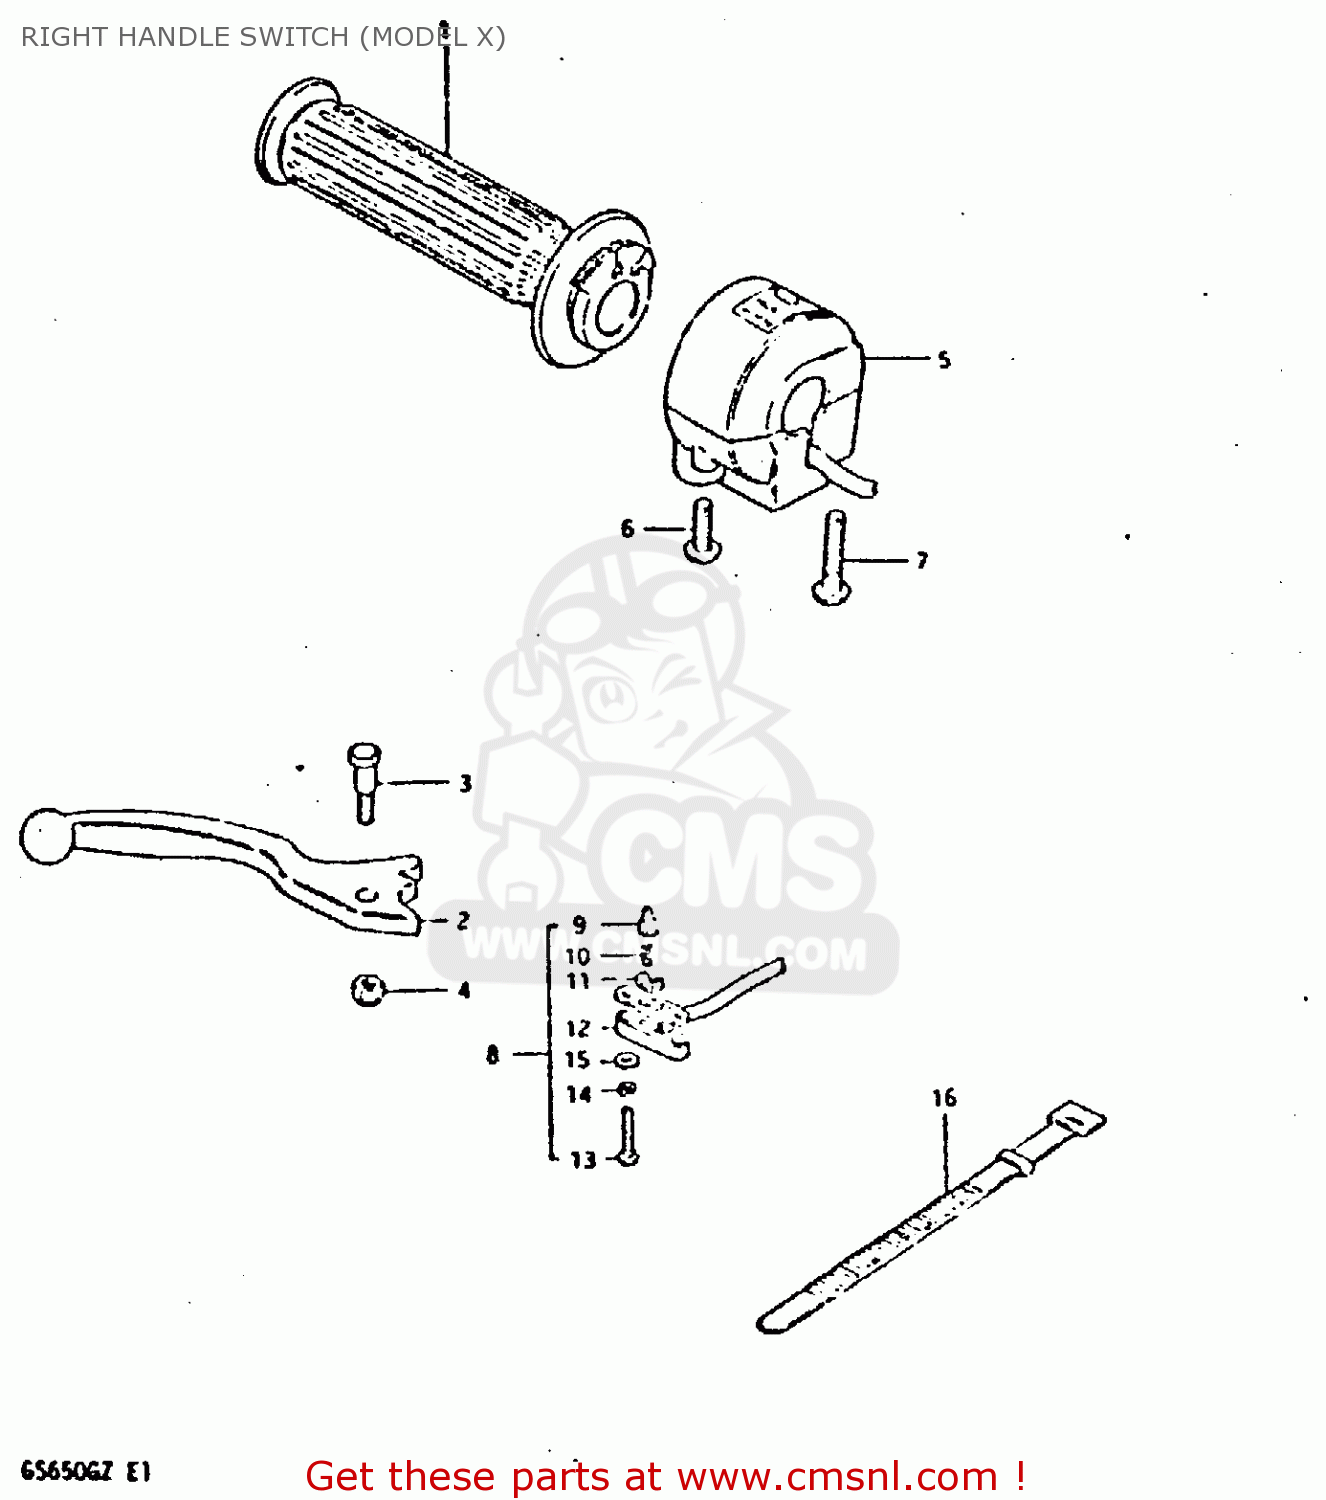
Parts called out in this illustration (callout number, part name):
1	GRIP,THROTTLE
2	LEVER,BRAKE
3	BOLT
4	NUT 6MM
5	SWITCH ASSY, HANDLE RH
6	SCREW
7	SCREW
16	CLAMP(L:120)
